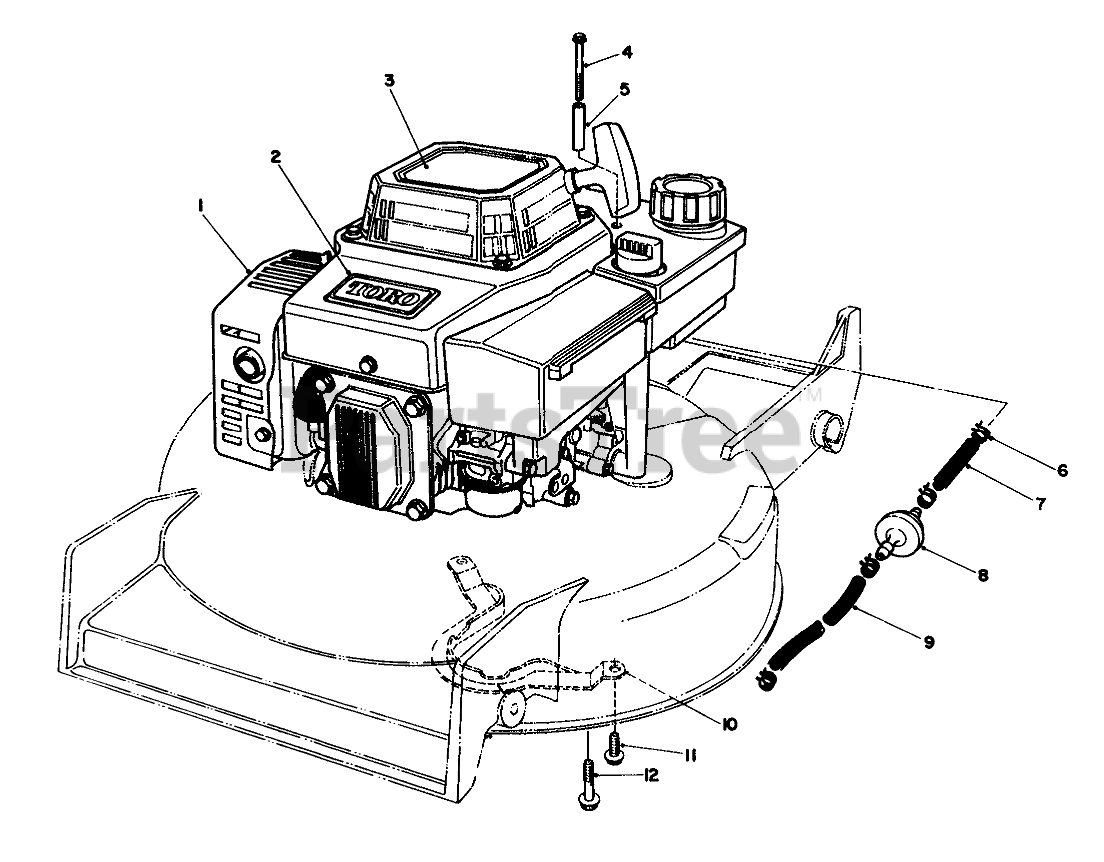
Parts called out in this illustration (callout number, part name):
1	Engine
2	TORO LOGO PLT
3	DECAL - RECOIL GTS
4	THRD FORMING SCREW
5	TUBULAR SPACER
6	CLAMP-FUEL LINE
7	LINE-GAS
8	FILTER-FUEL
9	HOSE-FUEL
10	BBC BELT GUIDE
11	SCREW-HWHTF
12	SCREW-HWHTF
